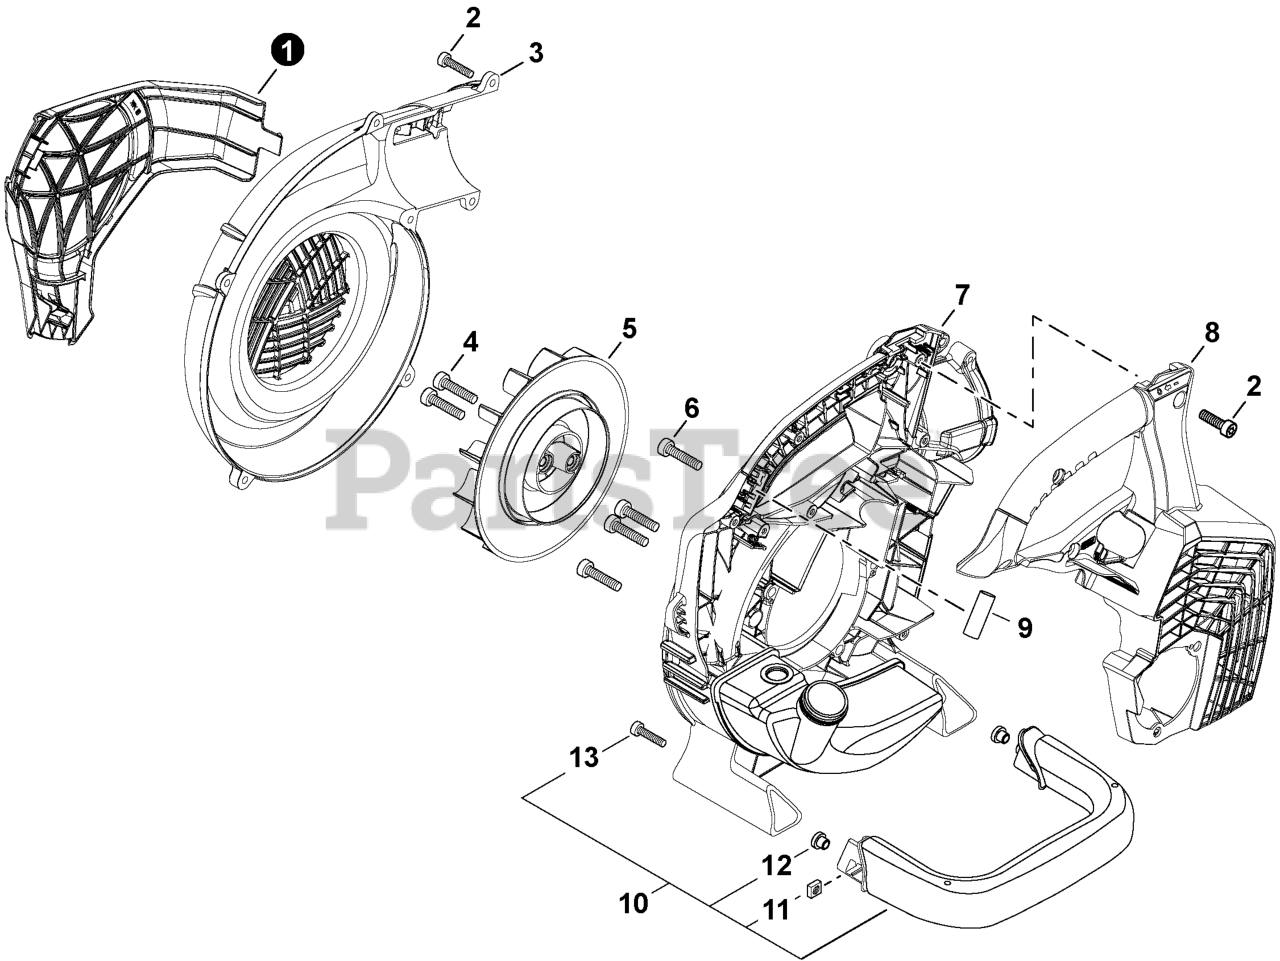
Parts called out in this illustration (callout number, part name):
1	GUARD, DEBRIS
2	BOLT, TORX 5x20
3	COVER, FAN CASE
4	BOLT, TORX 6x20
5	FAN, BLOWER
6	BOLT, TORX 5x16
7	CASE, FAN
8	COVER, ENGINE
10	HANDLE ASSY
12	COLLAR, 5
13	BOLT, TORX 5x20
